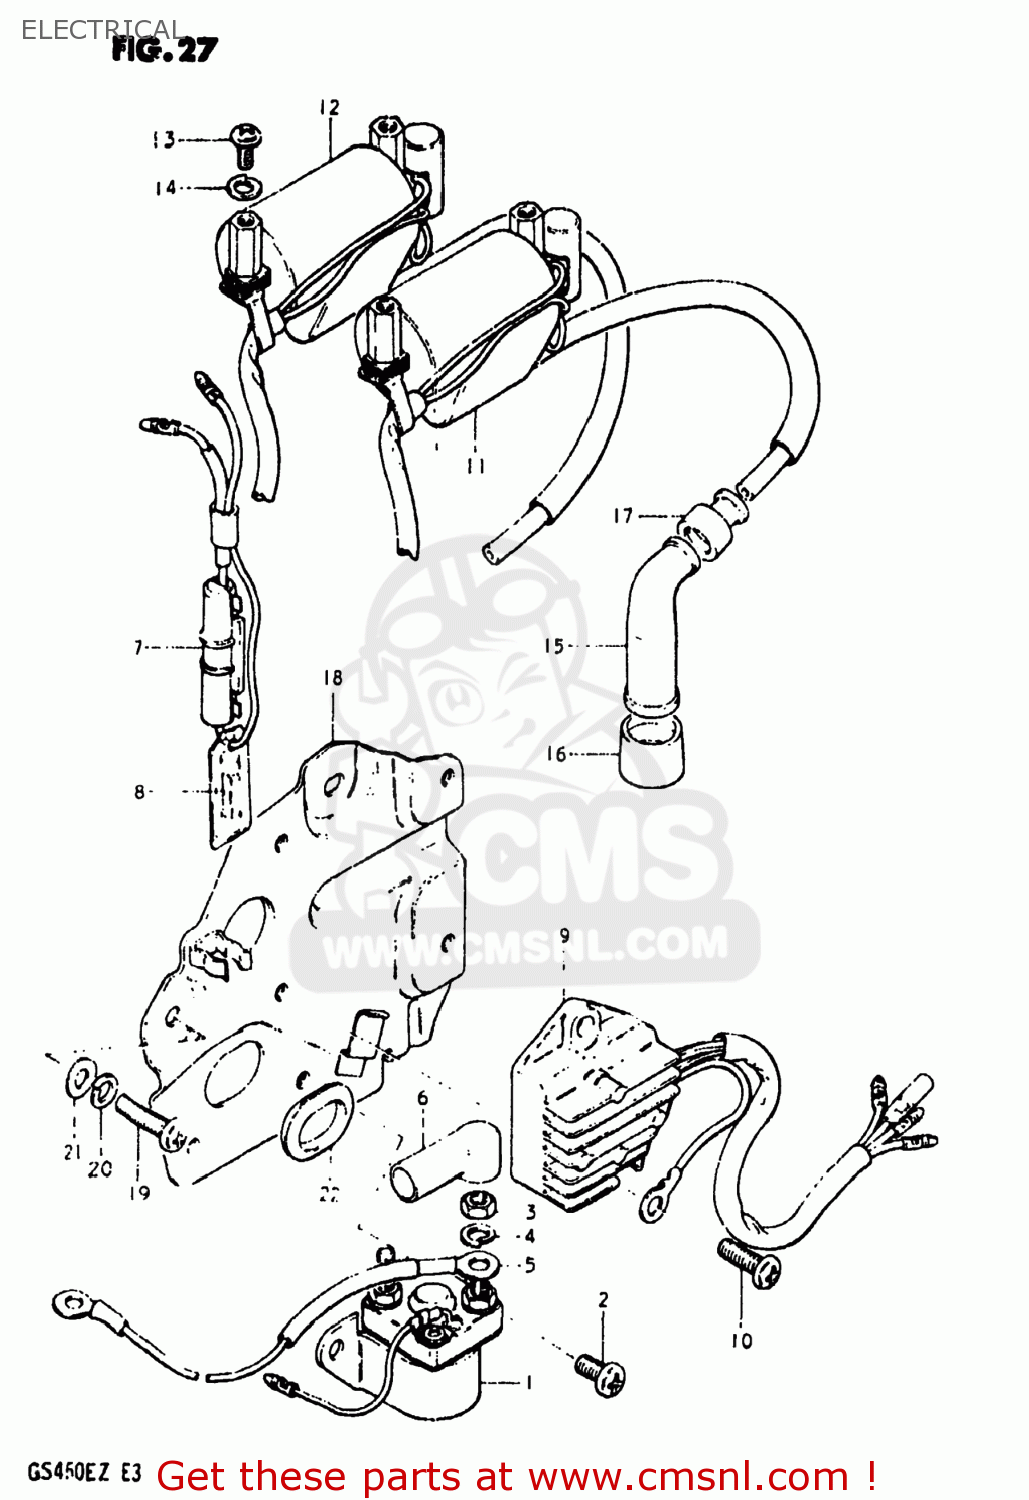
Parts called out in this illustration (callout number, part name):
1	RELAY ASSY,STARTING MOTOR
2	SCREW
3	NUT 6MM
4	LOCK WASHER
5	CORD,BATTERY MINUS
6	CAP,STARTER RELAY
7	BOX ASSEMBLY,FUSE
8	FUSE(15A)
9	RECTIFIER ASSEMBLY
10	SCREW
11	COIL ASSEMBLY,IGNITION
12	COIL ASSEMBLY,IGNITION
13	SCREW
14	LOCK WASHER
15	CAP,SPARK PLUG
16	SEAL,SPARK PLUG
17	SEAL,SPARK PLU
18	PLATE,ELECTRIC PARTS H
19	SCREW
20	LOCK WASHER
21	WASHER
22	GROMMET
